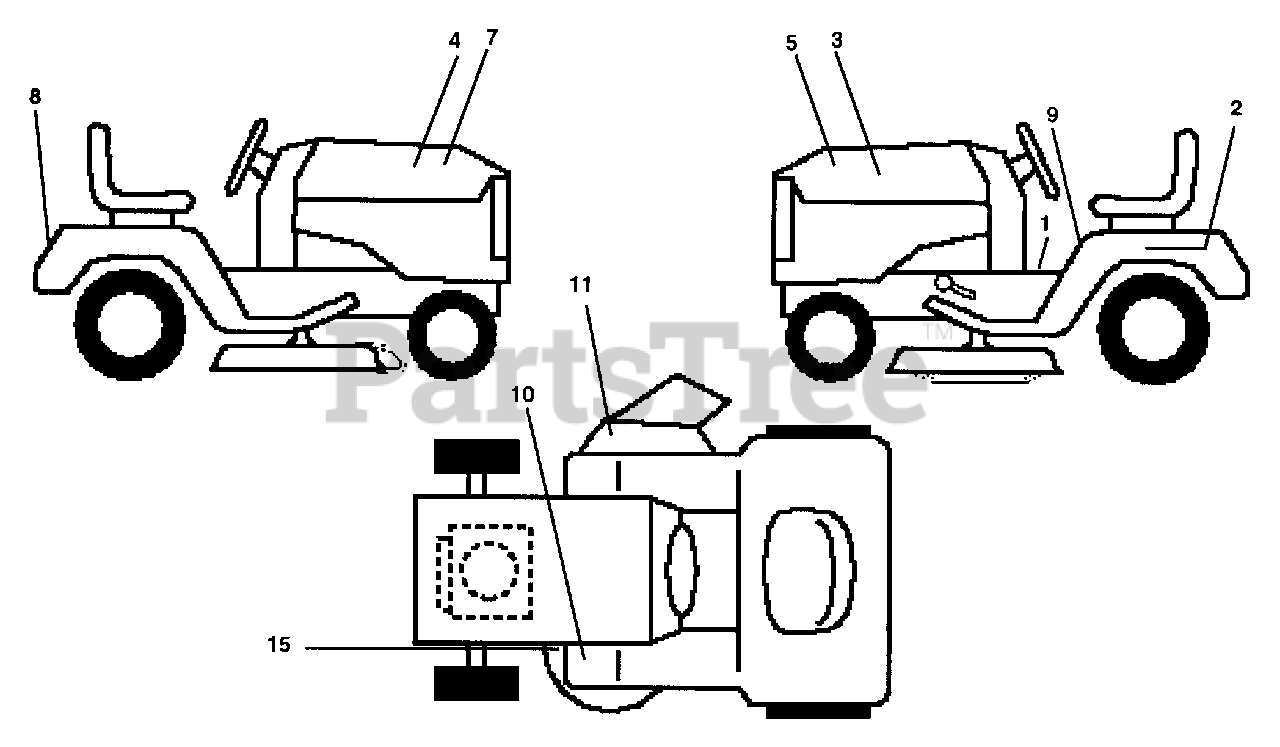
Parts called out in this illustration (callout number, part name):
1	Decal Instruction Dash Eng/fr
2	Decal Caution Battery Fr/ger
3	Decal Hood LH
4	Decal Hood RH
5	Decal Ins Hd LH
7	Decal Ins Hd RH
8	Decal Fender Logo
9	Decal Caution Fender Eng/fr
10	Decal Clutch/brake Eng/fr
11	Decal Warning Multi-Language
15	Decal V-Belt Schematic
